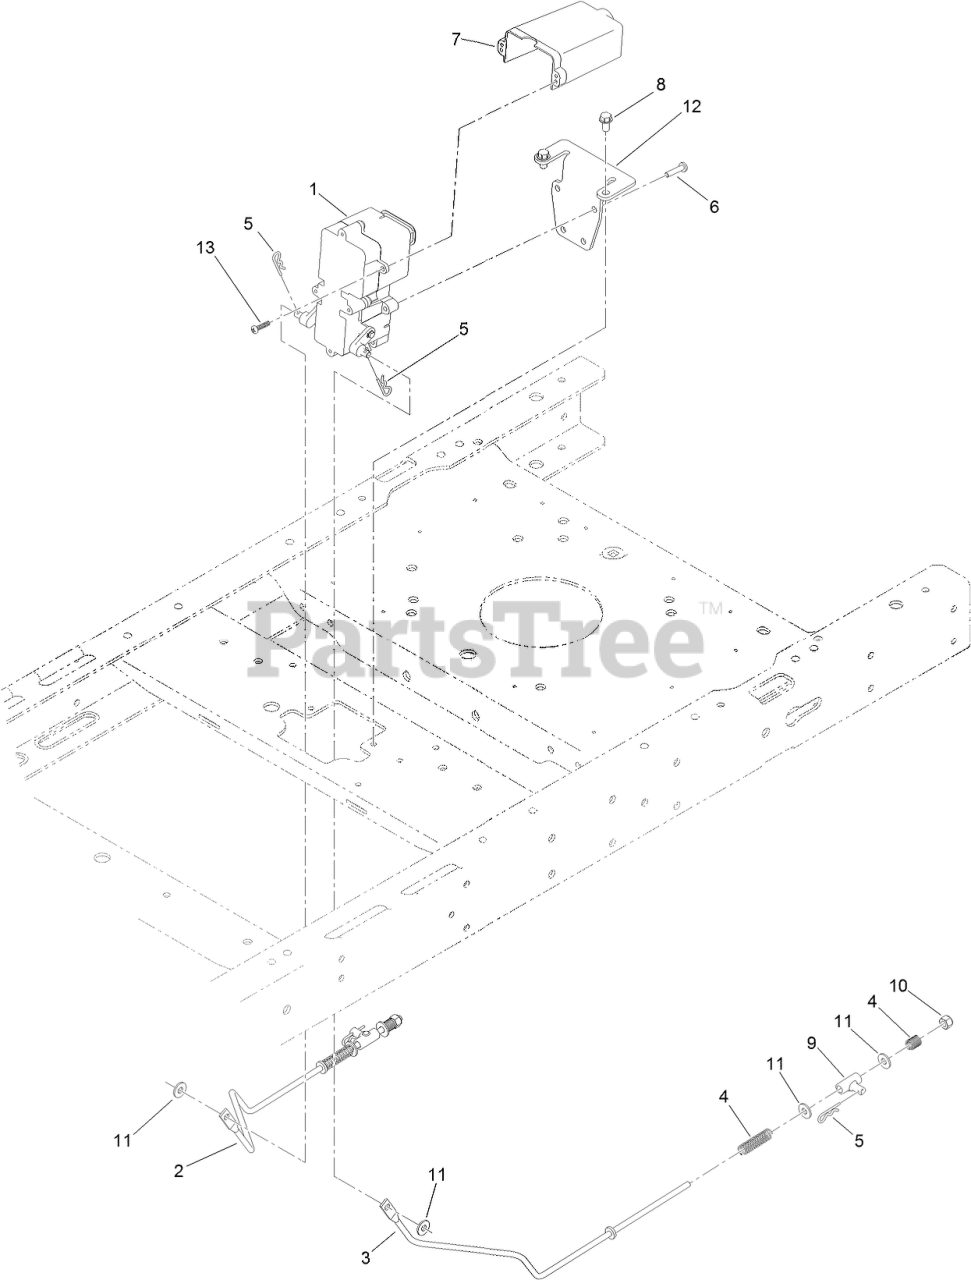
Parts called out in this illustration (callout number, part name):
1	BRAKE BOX ASM
2	ROD-BRAKE, RH
3	ROD-BRAKE, LH
4	SPRING-COMPRESSION
5	PIN-COTTER
6	SCREW-PPH
7	COVER-CONNECTOR
8	SCREW-HWH
9	MOUNT-PIVOT
10	NUT-LOCK, NI
11	WASHER
12	BRACKET-MOUNT, BRAKE
13	SCREW-PPH
